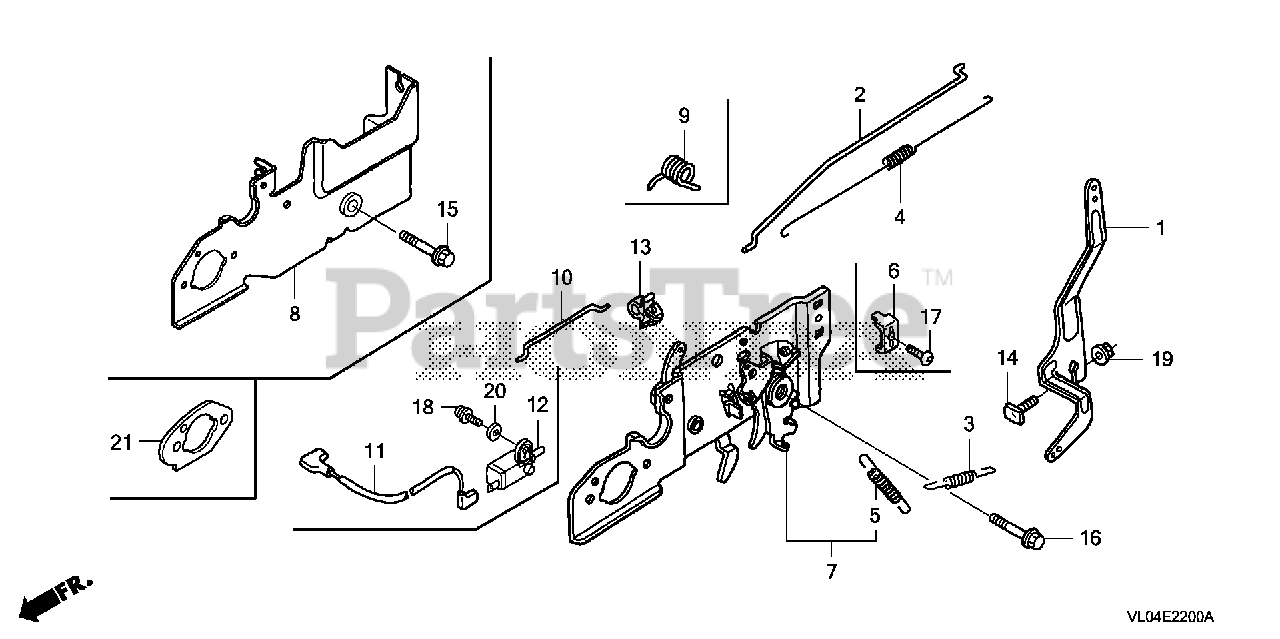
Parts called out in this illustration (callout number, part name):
1	ARM, GOVERNOR
2	ROD, GOVERNOR
3	SPRING, GOVERNOR
4	SPRING, THROTTLE RETURN
5	SPRING, LEVER
6	HOLDER, CABLE
7	BASE, CONTROL
9	SPRING, CONTROL LEVER RETURN
11	WIRE, STOP SWITCH
12	SWITCH ASSY., ENGINE STOP (N.O)
13	HOLDER, WIRE (FASTEX)
14	BOLT, GOVERNOR ARM
16	BOLT, FLANGE (6X50)
17	SCREW, PAN (5X16)
18	SCREW-WASHER (4X12)
19	NUT, FLANGE (6MM)
20	WASHER, PLAIN (4MM)
